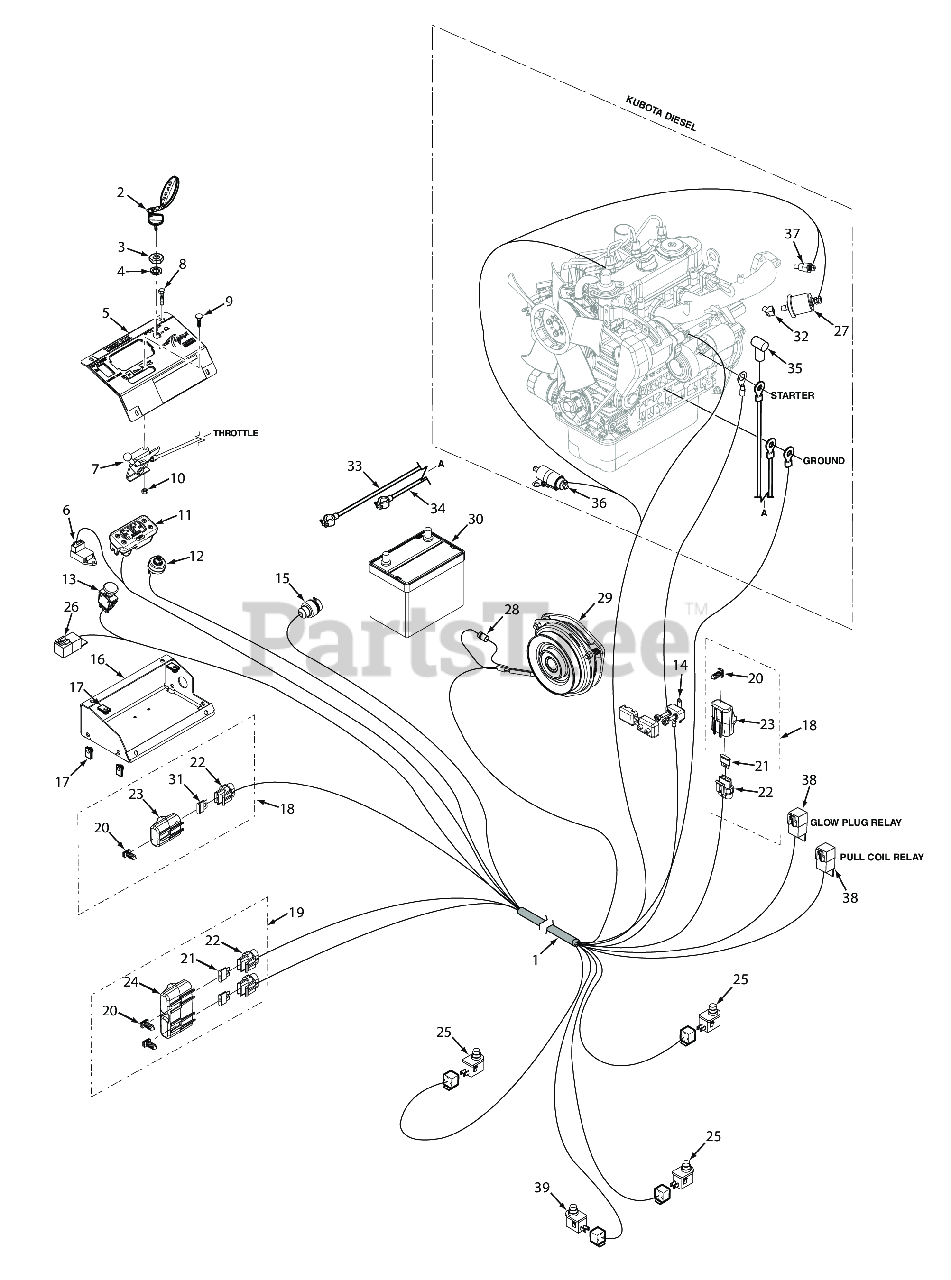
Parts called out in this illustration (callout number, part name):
1	Wire Harness, STTII-25KBD
2	Key, Assembly w/Fob
3	Nut, 5/8-32 Special
4	LOCK WASHER, 5/8" INTERNAL TOOTH
5	Instrument Panel w/Decal
6	Timer, Glow Plug
7	Cable, Control (Throttle)
8	Bolt, Hex Head Serrated Flange 1/4-20 x 3/4"
9	Bolt, Carriage #10-24 x 1/2"
10	Nut, Elastic Stop #10-24
11	Tiger Eye, Cluster Gauge
12	KEY SWITCH(INCLUDES MOUNTING HARDWARE)
13	Switch, PTO - 10 Amp
14	Circuit Breaker, 50 AMP
15	Power Plug, 12V
16	Base, Instrument Panel
17	Bolt, Hex Head 3/8-16 x 1"
18	Single Fuse Assy., Excluding Fuse
19	Double Fuse Assy.
20	Clip, Fuse Holder
21	FUSE, 20 AMP BLADE TYPE AUTOMOTIVE
22	Fuse Holder Assembly
23	Cover, Sealed Single
24	Cover, Sealed Double
25	Switch, Interlock, Normally Open
26	Relay, 12V 40 AMP Standard
27	Sender Unit, Oil Pressure
28	Diode, 600V 6 Amp
29	Clutch Assembly, GT3.5 (Diesel Engine)
30	Battery, 525 CCA
31	Fuse, 5 Amp
32	Elbow, 45 Degree Street
33	Battery Cable, 14" Red w/Braid
34	Battery Cable, 21" Black
35	Boot, Positive Battery Terminal
36	Solenoid, Fuel Shut-Off
37	Temperature Sensor, Engine Coolant
38	Relay, 12V 40 AMP Hi Capacity
39	Plunger Switch, Single Pole
